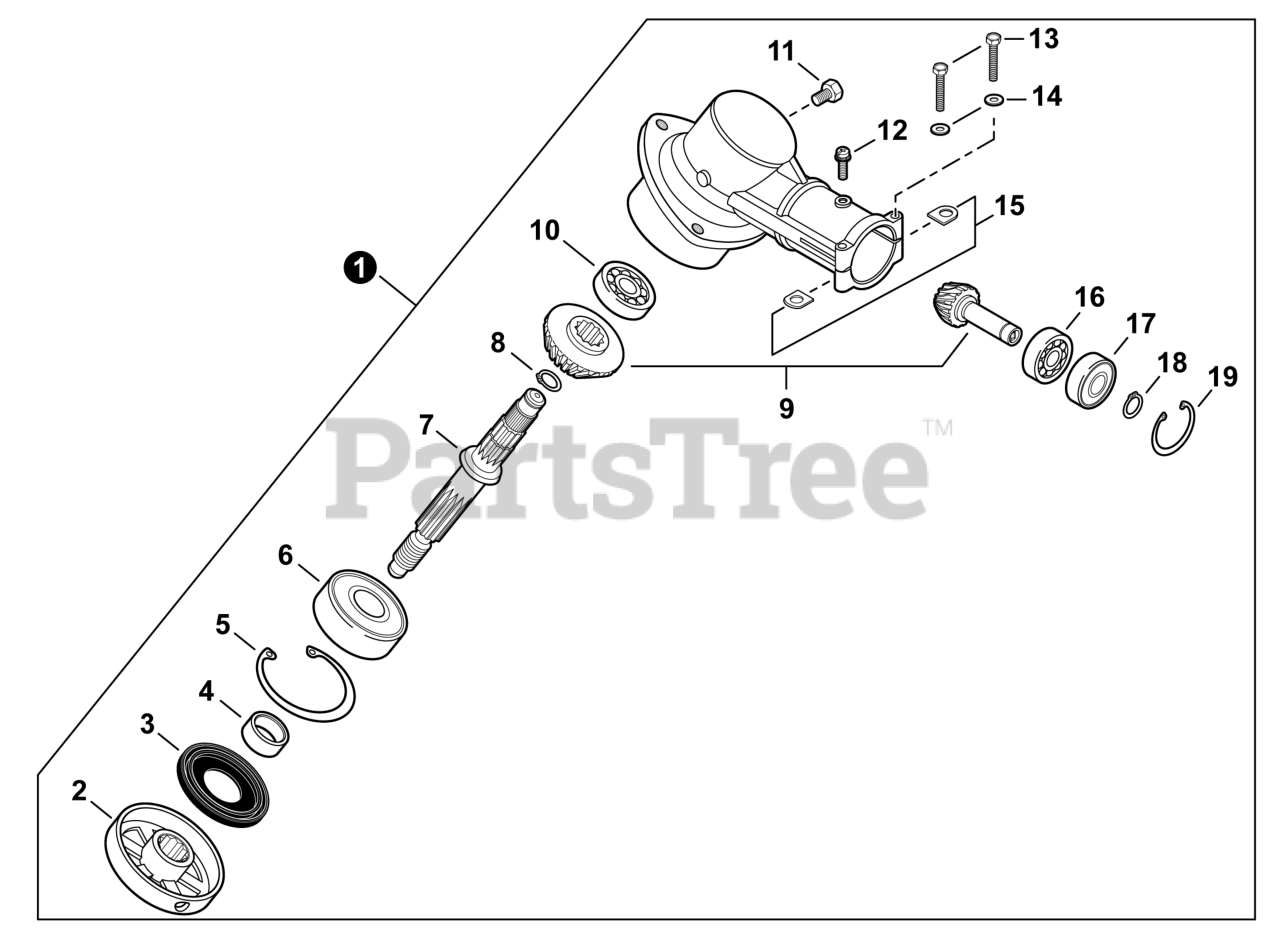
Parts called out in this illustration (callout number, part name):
1	GEAR CASE ASSY
2	PLATE, ADAPTOR - UPPER
3	SEAL, OIL 22
4	SPACER 11.8x15x9
5	RING, SNAP 32
6	BEARING, BALL 6201
7	SHAFT, GEAR
8	RING, SNAP 12
9	GEAR SET
10	BEARING, BALL 609
11	BOLT M8x8
12	SCREW 5x10
13	BOLT 5x35 SP
14	WASHER, FLAT 5.5x10x0.8
15	D-WASHER
16	BEARING, BALL 6900
17	BEARING, BALL 6900Z
18	RING, SNAP 10
19	RING, SNAP 22
